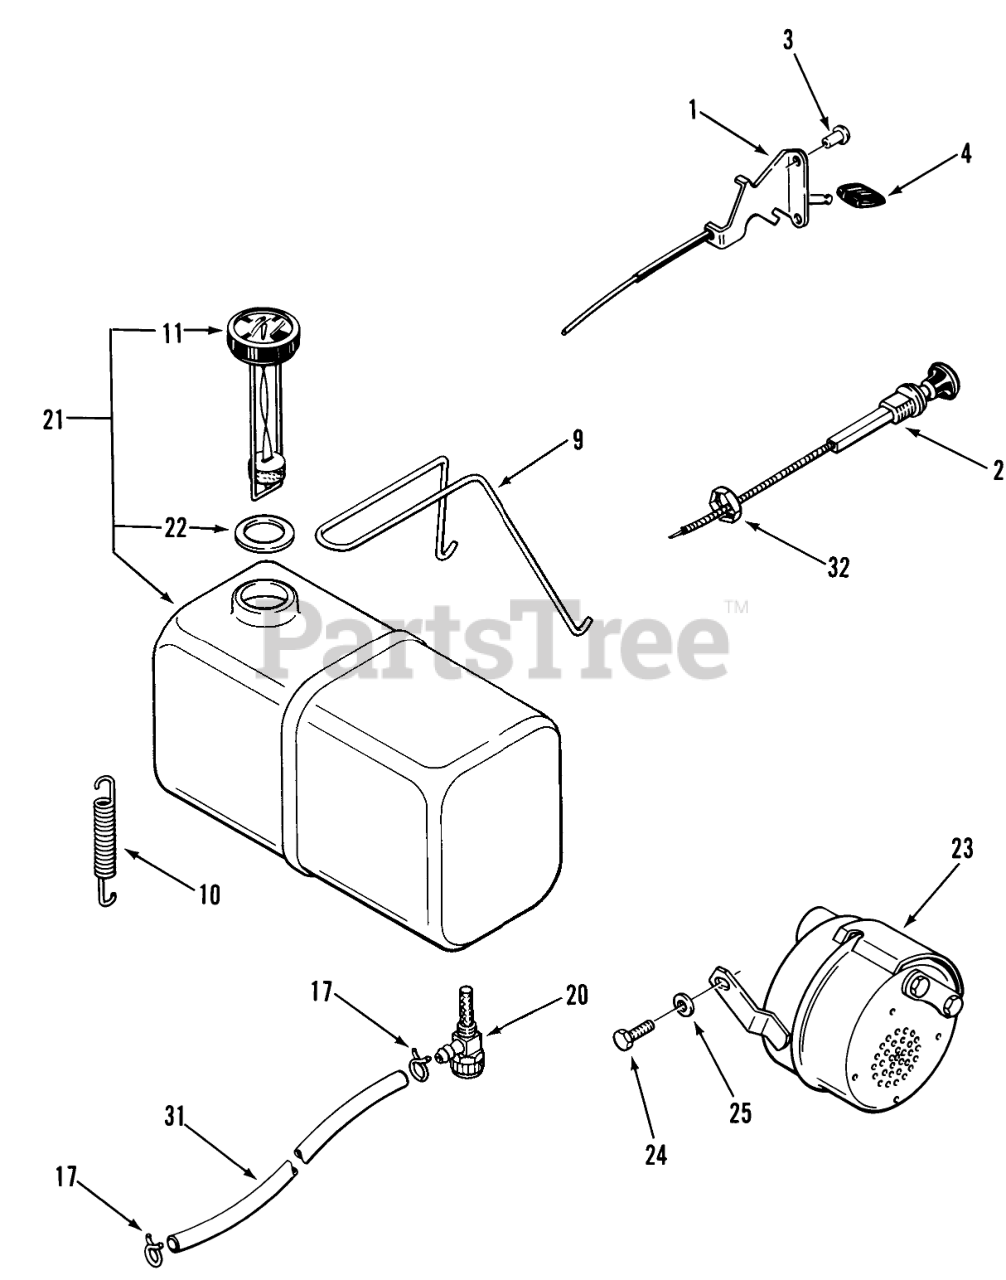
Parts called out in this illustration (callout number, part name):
1	CONTROL- THROTTLE
1	Choke/Throttle Control LT-1100 Only
2	CONTROL-CHOKE
3	RIVET-4
4	KNOB-THROTTLE
9	Hold Down Wire
10	SPRING-EXTENSION
11	Gasoline Cap
17	Clamp
20	FILTER & VALVE ASSY
21	Fuel Tank Assy
22	Seal (Service Only)
23	ASSY-MUFFLER
24	Bolt
31	Skid Bracket
31	Fuel Hose 5 in. (12.7 cm) LT-1637, LT-1642 Only
31	Fuel Hose 10.3 in. (26.2 cm) LT-1032 Only
32	NUT-HEX PALNUT
